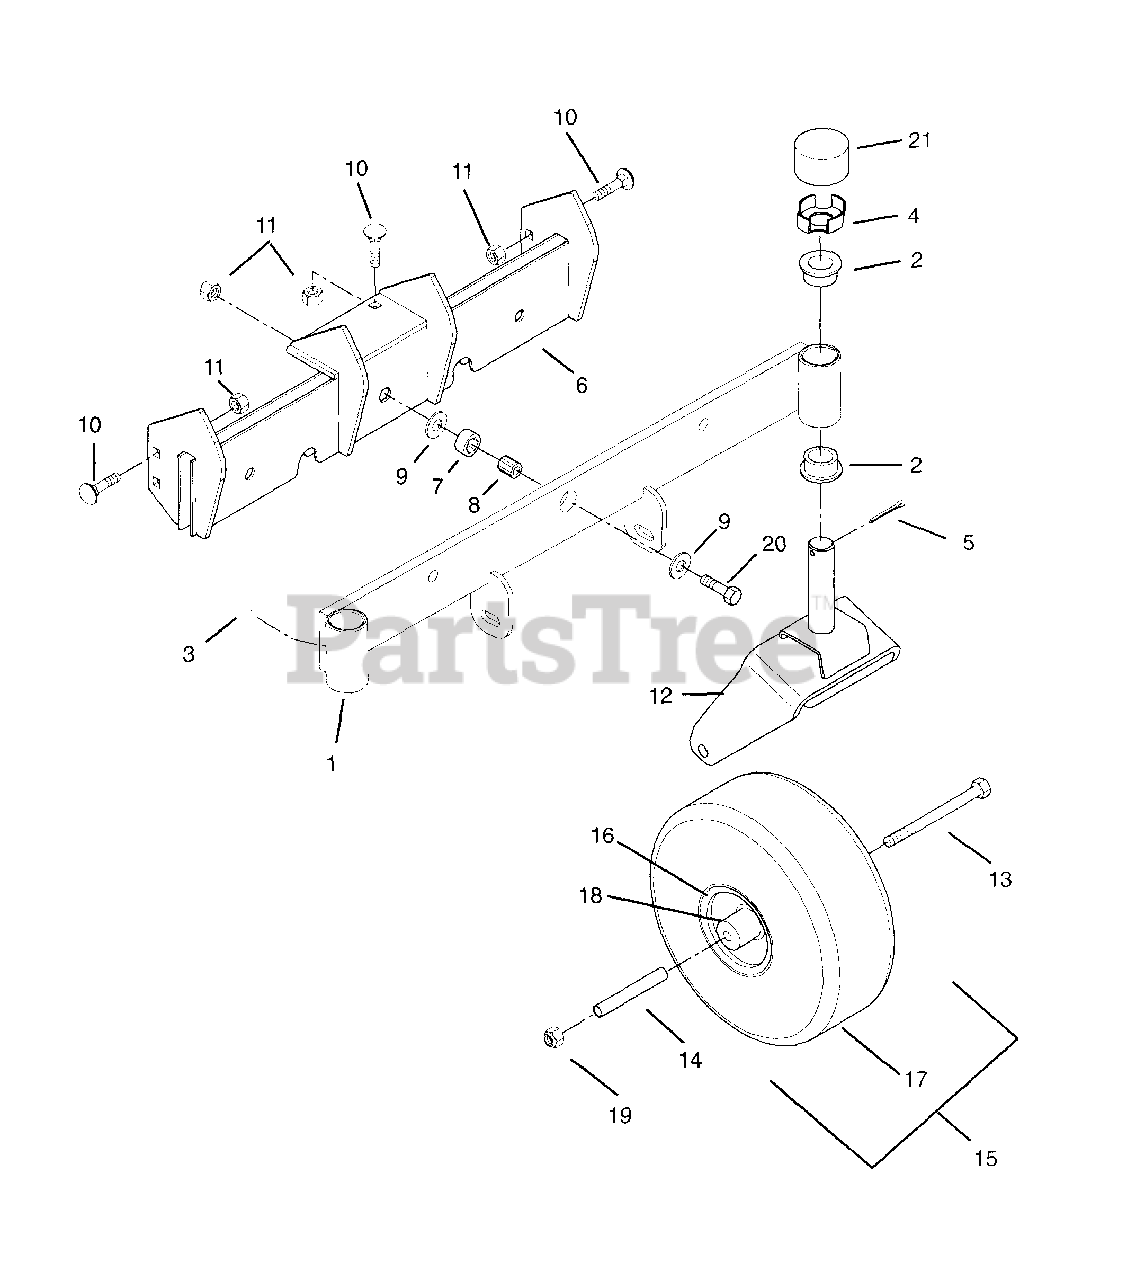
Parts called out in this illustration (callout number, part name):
1	AXLE WELDMENT
2	BSHG-FLG1.020X1.385X.75X1.75NY
3	FTG-LUBE .25-28X.256 YWZC
4	SPINDLE CUP
5	@PIN-CTR .18X1.50 EXTPRSQCT YZ
6	AXLE FRAME WELDMENT
7	BSHG-SLV .626X1.000X.524 HEX
8	BSHG-SLV .377X.623X.775 HEX
9	WSHR-FL-STL .380X1.50X.125YWZC
10	@BLT-RDHDSQNK .38-16X.75 G2YWZ
11	@NUT-LK-CTR .38-16 YWZC
12	CASTER FORK WELDMENT
13	@BLT-HEX .50-13X6.50 GR5 YWZC
14	BUSH.,CASTER FORK
15	T/WHL 11X4.00-5 RIBBED
16	RIM ASSY 11X4.00-5
17	TIRE RIBBED 11X4.00-5
18	RIM BEARING-11X4.00-5 RIM
19	@NUT-LK-CTR .50-13 YWZC
20	@BLT-HEX .38-16X1.50 GR5 YWZC
21	HUB CAP
